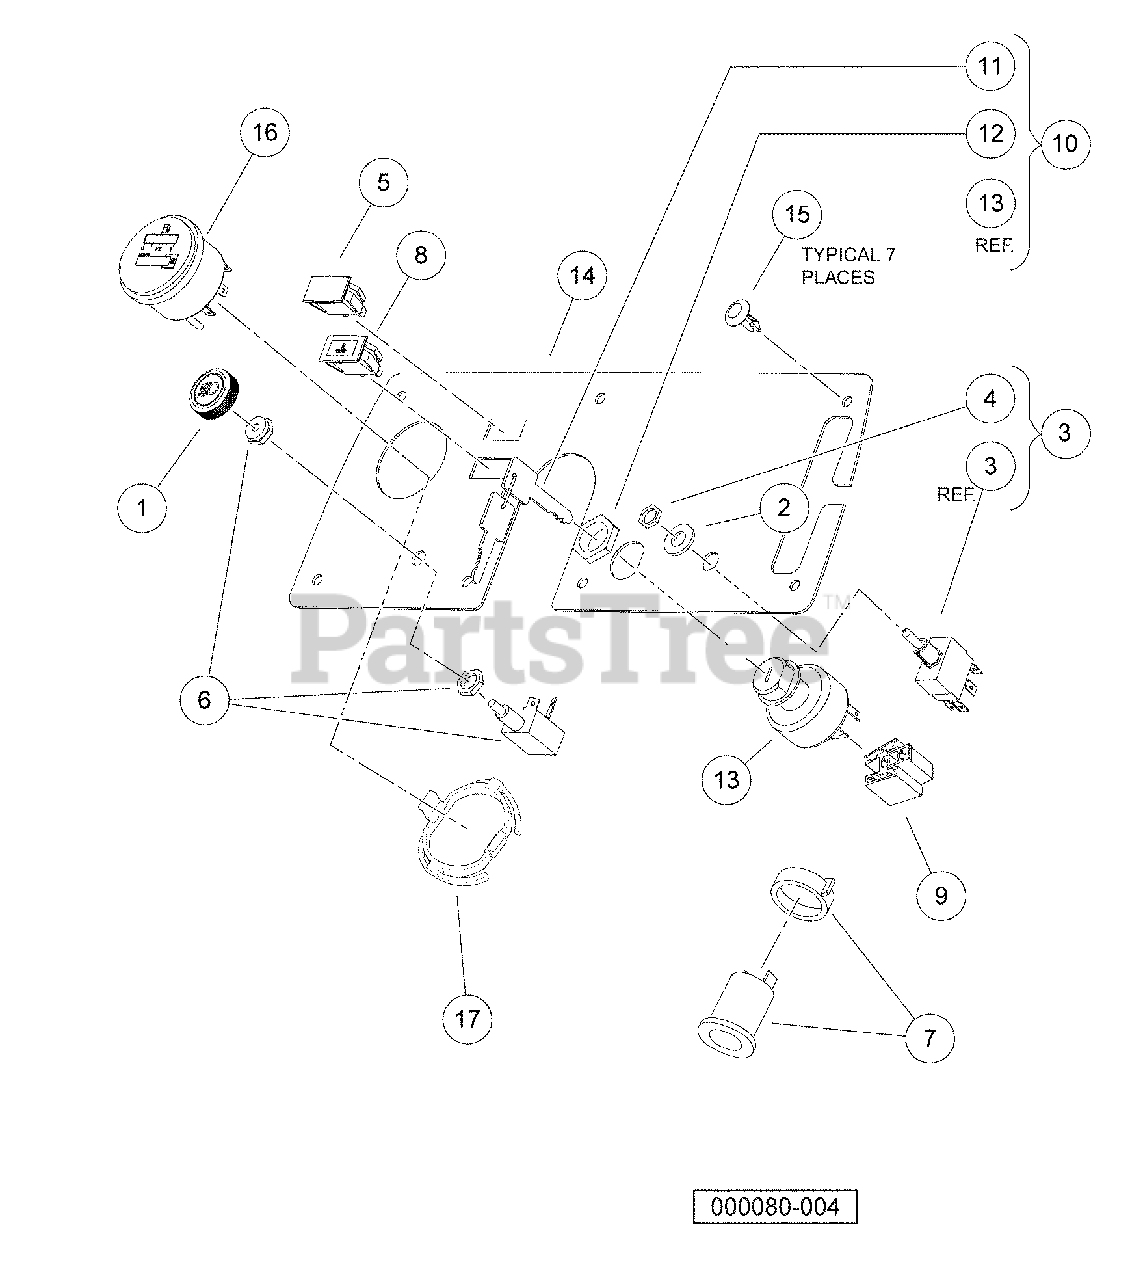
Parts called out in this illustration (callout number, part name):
1	Knob, Light Switch
2	Washer, 7/16 Flat
3	Toggle Switch
4	Nut, Toggle Switch
5	Light, Oil
6	Switch, Light
7	Receptacle, Accessory
8	Light, Indicator, Coolant Temp
9	Connector, 6 Way, 56 Series
10	Switch, Key
11	Key Set (1 pair)
12	Nut, Key Switch
13	Switch, Key without Nut
14	Panel, Instrument - Diesel
15	Rivet, Removable, Tuflok 1/4"
16	Gauge Fuel-hour Sep Gnd
17	Clip, Meter, Round
